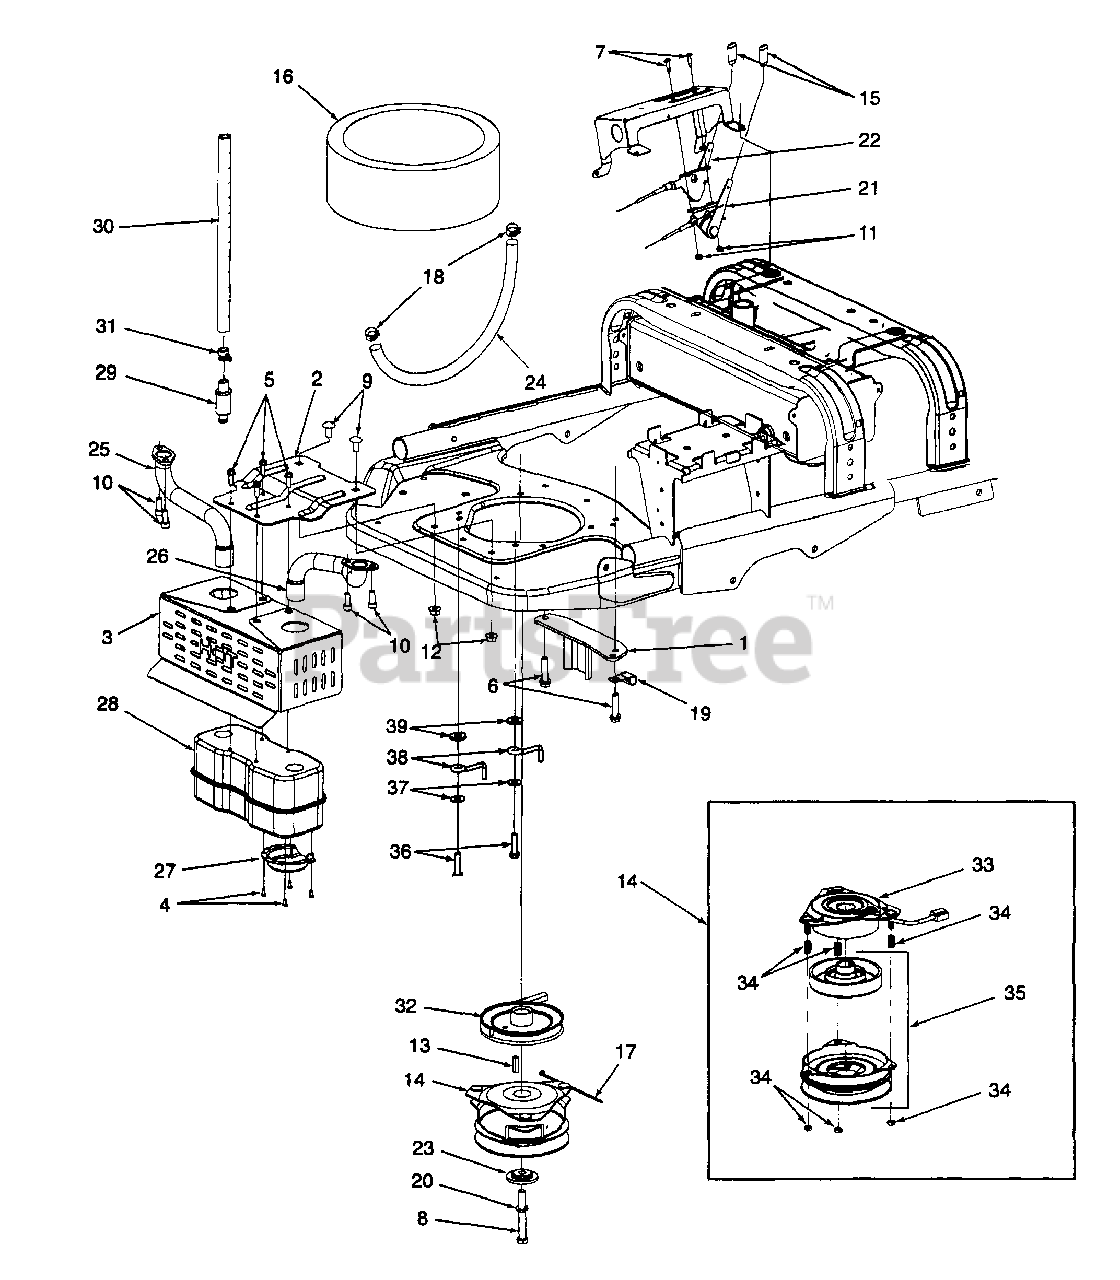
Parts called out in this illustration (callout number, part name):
5	Screw, Hex Wash Hd Tapp 1/4-20 x .75
6	Screw, Hex Wash Hd Tapp 3/8-16 x 1.5
7	Screw, Phil. Pan Hd, 10-24 x .75
8	Screw, Hex Cap 7/16-20 x 3.25 GR5
9	Bolt, Carriage, 3/8-16 x .75
10	Screw, Socket Hd M8 x 1.25 x 20 mm
11	Nut, Hex, #10-24
12	Nut, Hex Flange Lock, 3/8-16
13	Key, Square, 1/4 x 1.0
14	Clutch Assembly, PTO
16	Seal Ring, Foam Gasket
20	Washer, Lock, 7/16
21	Cable, Choke Control
22	Cable, Throttle Control
23	Spacer, PTO Clutch
24	Fuel Line Hose 13" Length
25	Tube, Exhaust - RH
26	Tube, Exhaust - LH
27	Deflector, Muffler
28	Muffler, Twin Inlet
29	Drain, Oil
30	Extension Hose, Oil Drain 13" Lg
31	Cap, Oil Drain
32	Pulley, Transmission Drive
33	Field Assembly
34	Kit. Spring and Nut
35	Armature/Rotor Assembly
36	Screw, Hex Wsh. Hd. Tapp 3/8-16 x 1.88
37	Washer, Flat
38	Rod, Rear Belt Retaining
39	Washer, Flat
